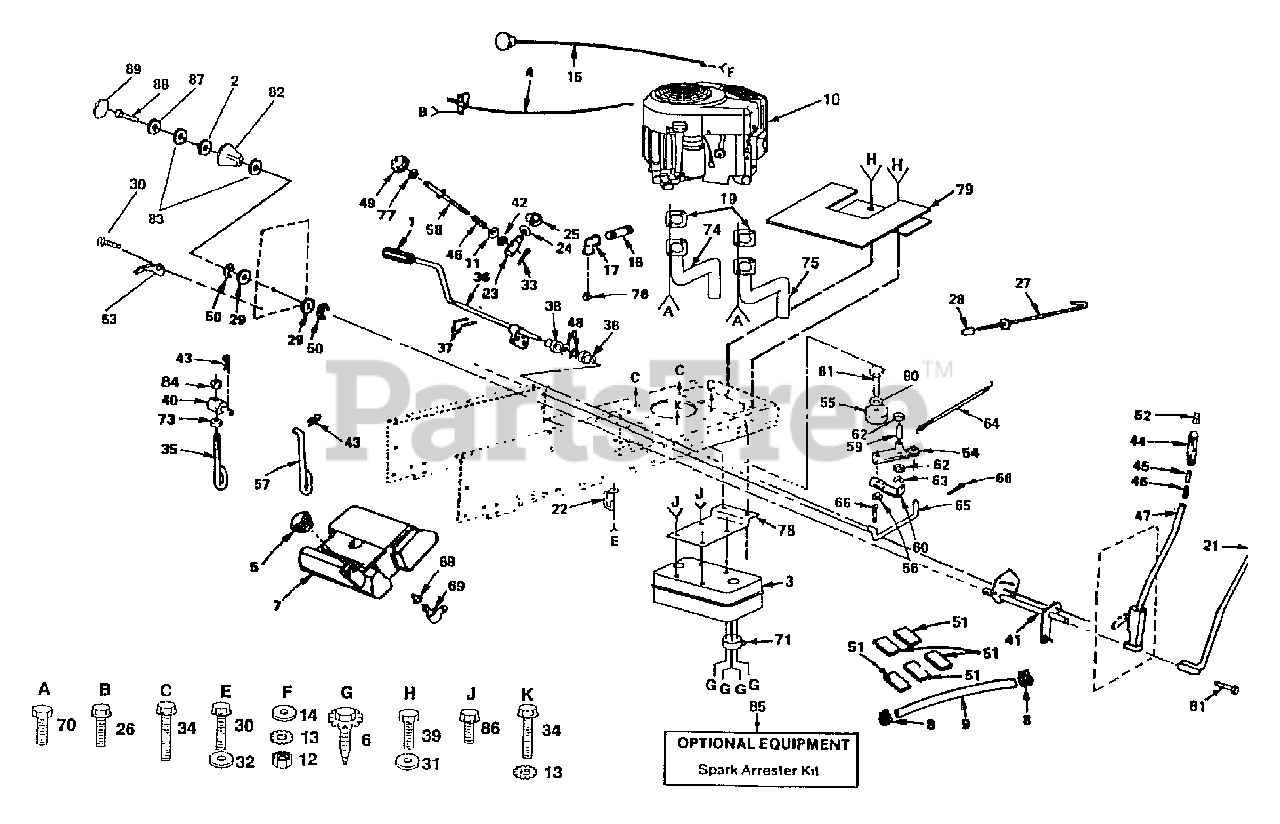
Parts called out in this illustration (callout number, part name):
1	Cover, Foot Pedal
2	Washer, Nylon
4	Control, Throttle
6	Screw, Spider Lock
7	Tank, Fuel
8	Clamp, Hose
9	Line, Fuel
10	Engine, Briggs & Stratton, Model Number 303777
11	Washer 13/32 x 5/8 x 16 Gauge
12	Nut, Hex 3/8-24
13	Washer, Lock, External Tooth 3/8
14	Washer 13/32 x 13/16 x 16 Gauge
15	Control, Choke
16	Nipple, STD Pipe
17	Elbow, 90° 3/8 NPT
19	Gasket, Muffler
21	Rod Assembly, Lever
22	Retainer, Belt, Chassis, L.H.
23	Trunnion, Stop, Depth
24	Washer 15/32 x 3/4 x 16 Gauge
25	Ring, Klip
26	Screw, Hex Washer Hd. Thread Cutting 1/4-20 x 1/2
27	Rod, Brake, Park
28	Cap, Plunger
29	Washer 29/32 x 1-1/4 x 16 Gauge
30	Screw, Hex Washer Thread Rolling 3/8-16 x 3/4
31	Washer 13/32 x 1 x 14 Gauge
32	Washer 13/32 x 1-3/16 x 16 Gauge
33	Pin, Cotter 3/32 x 1/2
34	Screw, Hex Washer Hd. Thd. Rolling 3/8-16 x 1-1/2 Type TT
35	Lift, Link, Adjustable
36	Shaft, Pedal, Foot
37	Pin, Roll 3/16 x 1
38	Bearing, Nylon
39	Screw 5/16-18 x 3/4
40	Trunnion, Lift
41	Shaft Assembly, Lift
42	Nut, Special
43	Retainer, Spring
44	Grip, Handle
45	Plunger, Lever, Lift
46	Spring
47	Lever Assembly, Hand Kit
48	Washer 21/32 x 1 x 16 Gauge
49	Handle, Adjust, Lift
51	Pad, Spacer
52	Button, Plunger
53	Pointer, Height Indicator
54	Arm Assembly, Idler
55	Pulley, Idler
56	Locknut 3/8-16
57	Link, Lift
58	Rod, Adjust, Lift
60	Retainer, Belt
61	Bolt, Hex 3/8-16 x 1-1/2
62	Washer, Hardened
63	Ring, Klip
64	Spring, Return, Clutch
65	Link, Clutch
66	Pin, Cotter 118 x 3/4
68	Bushing
69	Stem, Tank, Fuel
70	Bolt, Metric
71	Deflector, Muffler
73	Nut, Hex, Jam 7/16-20
74	Tube Assembly, Exhaust, L.H.
75	Tube Assembly, Exhaust, A.H.
76	Plug, Drain, Oil
77	Nut, Hex, Jam 3/8-16
78	Bracket, Muffler, Mounting
79	Shield, Heat
80	Washer 13/32 x 13/16 x 16 Gauge
81	Bolt, Hex 3/8-16 x 1-1/2
82	Scale, Height Indicator
83	Washer 11/32 x 1-1/2 x 10 Gauge
84	Nut, Crownlock 7/16-20
85	Spark Arrestor Kit
86	Screw, Hex Washer Hd. Thread Cutting 1/4-20 x 1/2
87	Washer, Lock
88	Bolt, Hex 5/16-18 x 1
89	Plug, Hole
